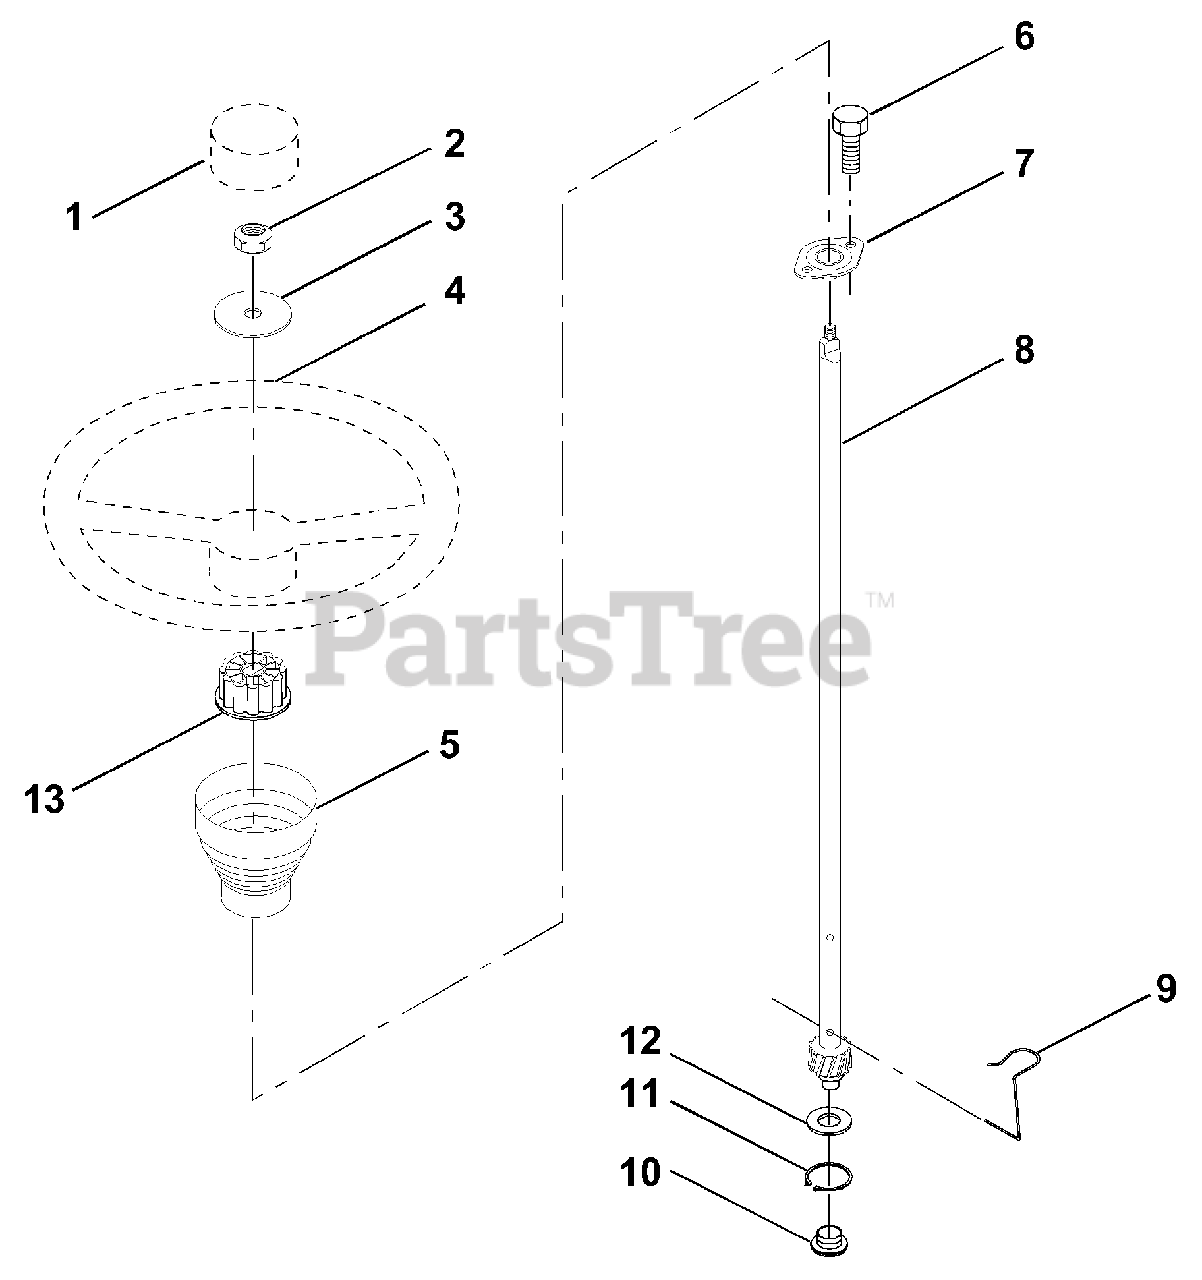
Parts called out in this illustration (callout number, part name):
1	Insert, Steering Wheel
2	Locknut 3/8-24 UNF
3	Washer 12/32 x 2-3/8 x 8 Gauge
4	Steering Wheel
5	Sleeve, Steering
6	Screw, Hex Head #10-16 x 1/2
7	Bushing, Steering
8	Shaft, Steering
9	Clip, Steering
10	Bushing, Lower, Steering
11	Ring, Retaining
12	Washer 21/32 x 1 x 16 Gauge
13	Adaptor, Steering Wheel
